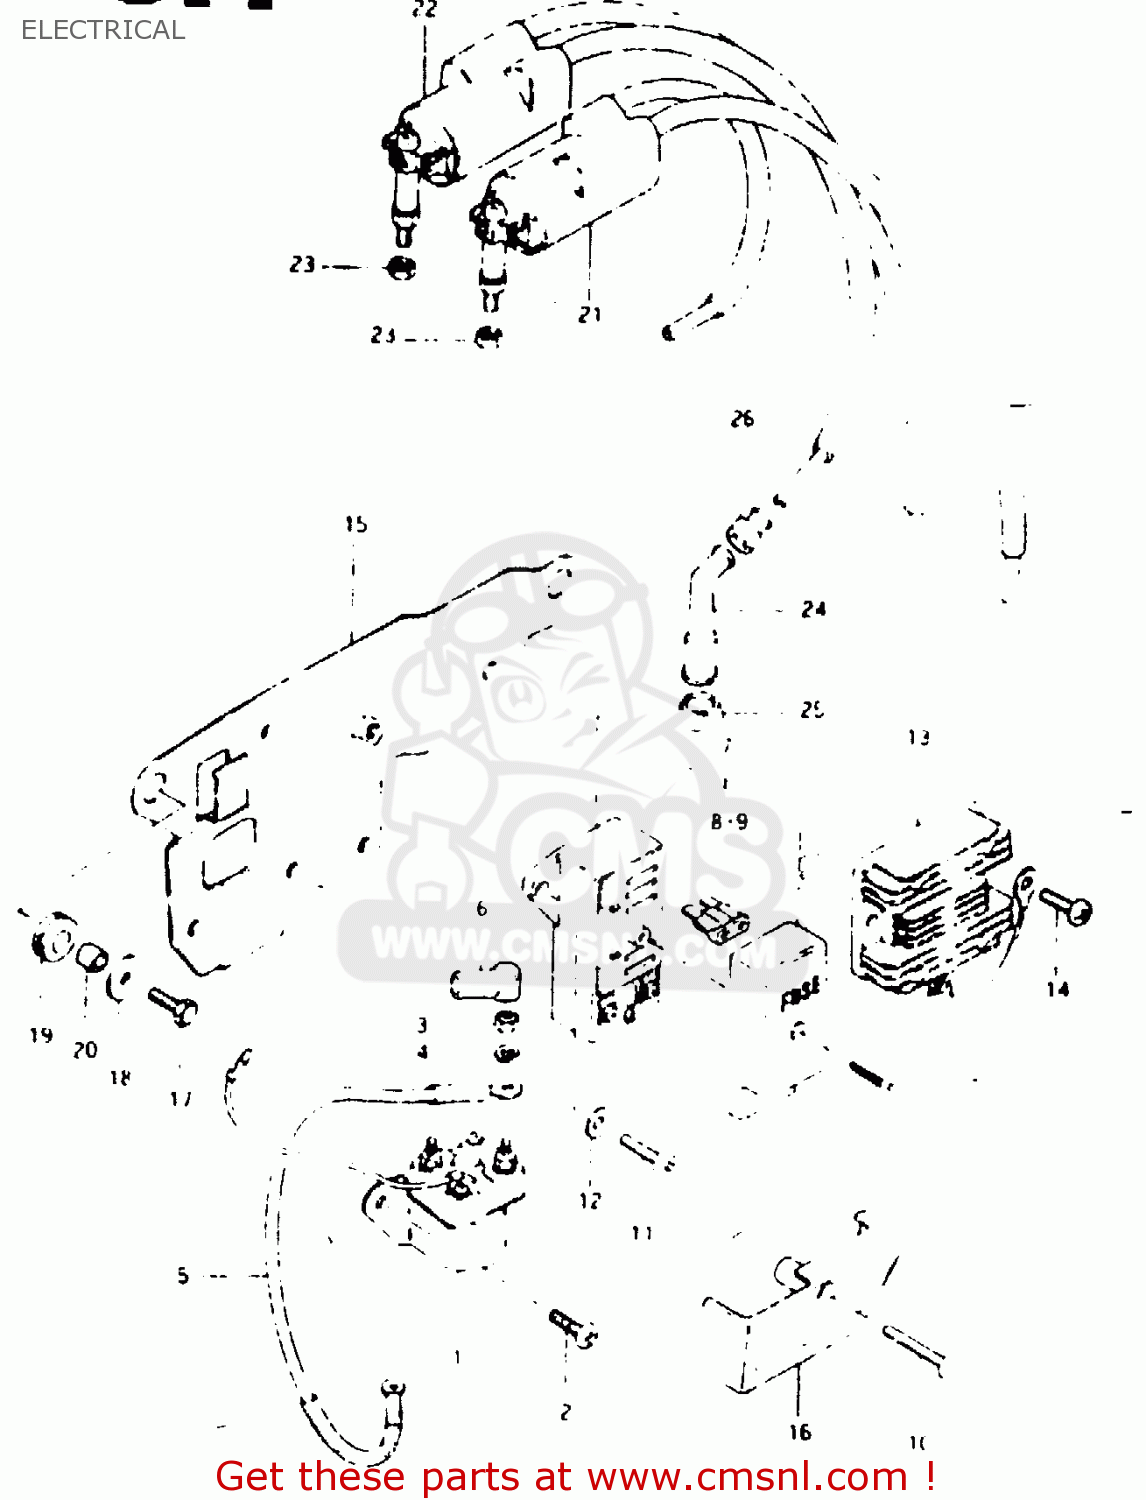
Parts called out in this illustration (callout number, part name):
1	RELAY, STARTING MOTOR
2	SCREW
3	NUT 6MM
4	LOCK WASHER
5	CORD,BATTERY MINUS
6	CAP,STARTER RELAY
7	BOX ASSEMBLY,FUSE
8	FUSE(10A)
9	FUSE(15A)
10	SCREW (6X35)
11	SCREW
12	WASHER
13	RECTIFIER, REGULATOR
14	SCREW 6X12
15	HOLDER COMP,ELECTRONIC PARTS
16	COVER,ELECTRIC PARTS HOLDER
17	BOLT, UPPER
18	WASHER (6.5X22X1.6)
19	CUSHION
20	SPACER (7X9X7)
21	COIL ASSEMBLY,IGNITION
22	COIL ASSEMBLY,IGNITION
23	NUT
24	CAP ASSY,SPARK PLUG
25	SEAL,SPARK PLUG
26	SEAL,SPARK PLU
